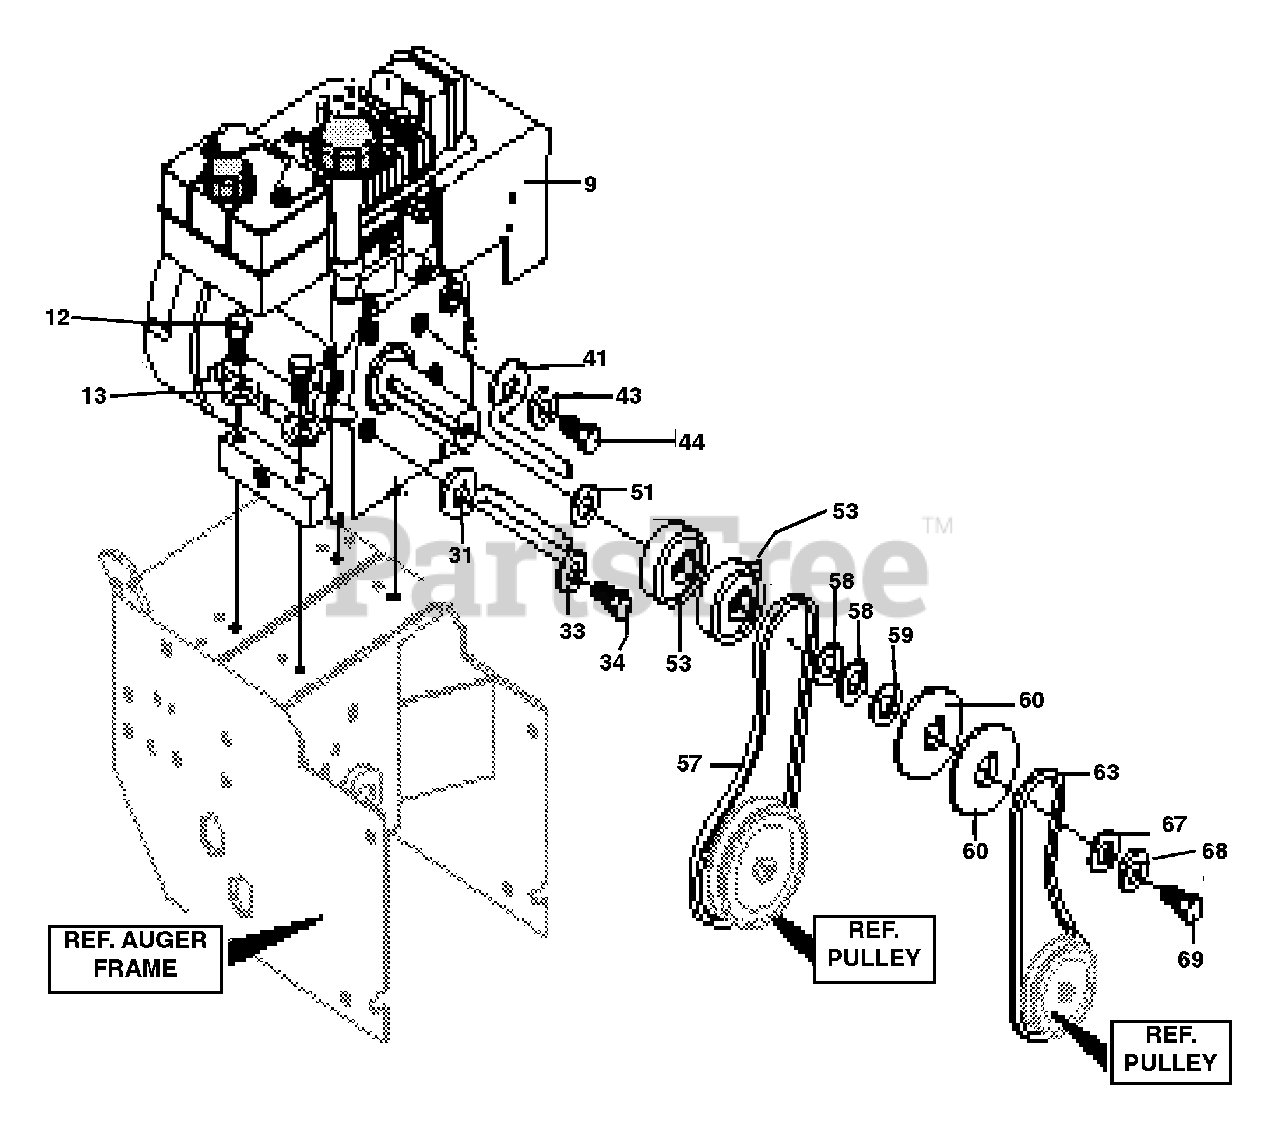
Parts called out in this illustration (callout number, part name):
12	SCREW, 5/16-18
13	WASHER, .328 X .60 X .09
31	GUIDE, ROD BELT RH
33	WASHER, .328 X .60 X .09
34	SCREW, 5/16-24 X 1.00
41	GUIDE, ROD BELT RH
43	WASHER, .328 X .60 X .09
44	SCREW, 5/16-24 X 1.00
51	WASHER, CRANKSHAFT
53	PULLEY, HALF
57	BELT, V 3L 33.13 LG
58	FLATWASHER .765 X 1.12 X .06
59	SPACER, SLEEVE
60	PULLEY, ENGINE
63	BELT, V 4L 35.23 LG
67	WASHER, FLAT
68	WASHER, .393 X .68 X .10
69	SCREW, 3/8-24 X 1.00
